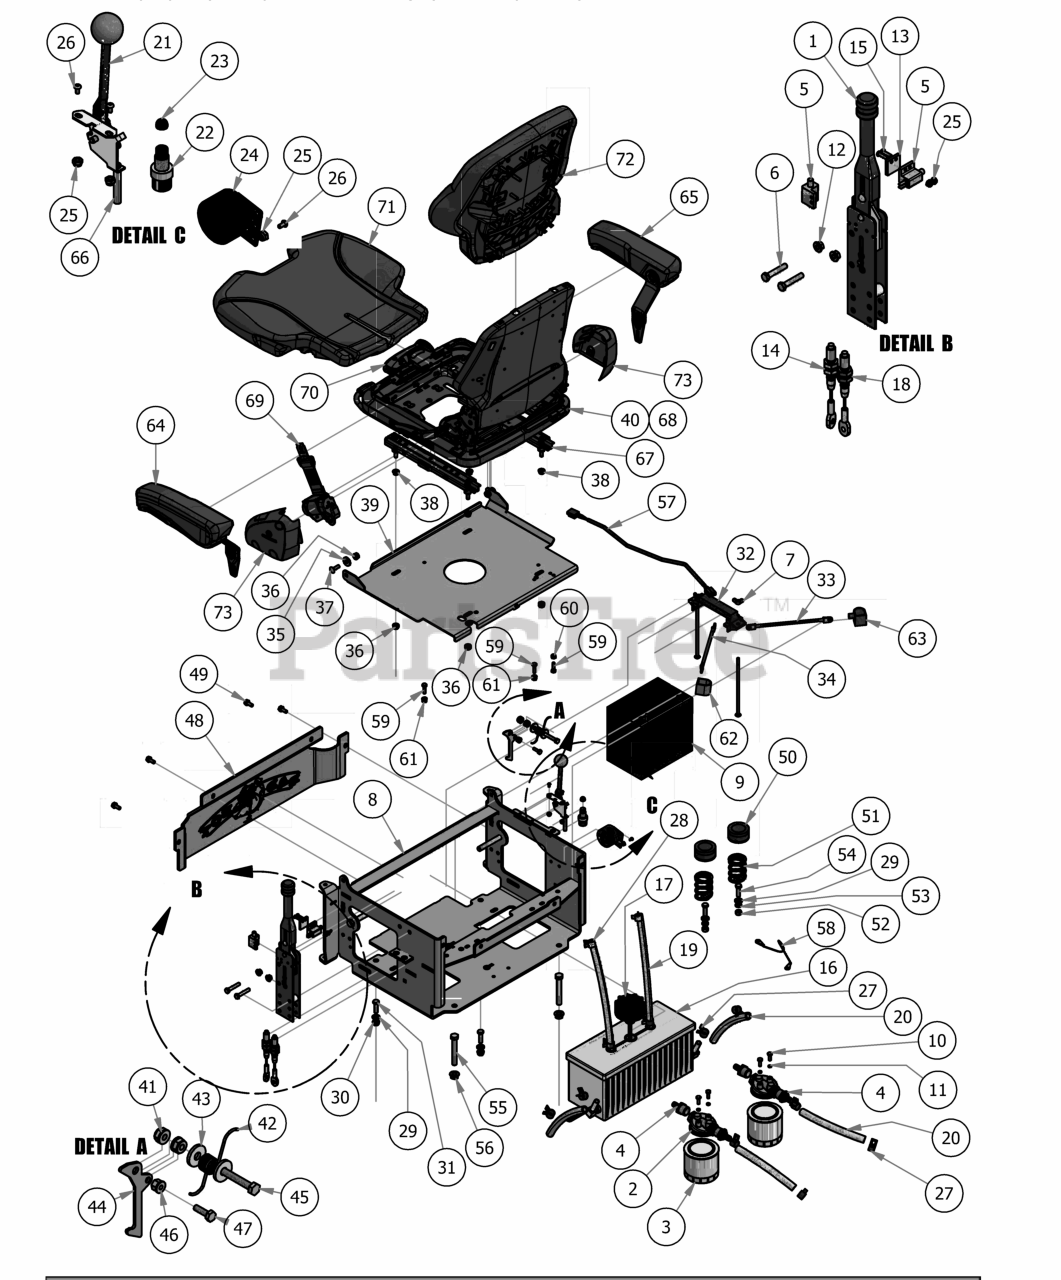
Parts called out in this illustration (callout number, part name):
1	Hand Brake Assembly
2	Filter Head
3	Hydraulic filter
4	Filter Head Fitting
6	5/16" x 1 3/4" Hex Bolt
7	1/4" Wing Nut
8	2007 Diesel Seat Frame
9	Battery - Diesel Models - I51
10	1/4" x 3/4" Hex Bolt
11	1/4" Lock Washer
12	5/16" Flange Nut w/Serrations
13	Switch Block Plastic
14	Short Brake Cable
15	1024 x 1" Allenhead Bolt
16	Aluminum Hydraulic Tank
17	Hydraulic Tank Cap
18	Long Brake Cable
19	3/8" x 32" Clear Hose
20	1/2" x 9 1/4" Braided Hose
21	Universal Throttle Head
22	Momentary Start Switch
23	Start Switch Boot - Diesel
24	Heat Warning Piezo Buzzer
25	#10 Nylock Nut
26	1024 X 5/8" Buttonhead Bolt
27	1/2 Hose Clamp
28	3/8 hose clamp
29	3/8" Flat Washer
30	3/8" Flange Nut
31	3/8" x 1 1/4" Hex Bolt
32	Battery Hold Down
33	Black Battery Cable - Diesel
34	Red Battery Cable - Diesel
35	.360 ID Plastic Washer
36	5/16-18 Nylon Flange Nut
37	5/16" x 1" Carriage Bolt
38	5/16" Flange Nut
39	Seat Plate
40	Grammer Seat With Seatbelt
41	5/16-18 Nylon Flange Nut
42	Torsion Spring for Seat latch
43	.360 ID Plastic Washer
44	Seat Latch Lever
45	5/16-18 X 2 Hex C/S (GR.5) ZC
46	1/4-20 Nylon Insert flange Nut
47	1/4-20 x 1-1/4 GR 5 Hex Bolt
48	Cooler Cover
49	5/16 x 3/4 washer head type F screw
50	Seat Spring Cap Cover
51	Seat Spring
52	3/8" Hex Nut
53	3/8" Lock Washer
54	3/8" x 1 1/2" Hex Bolt
55	1/2 x 3 1/2 Flange Bolt Grade 8
56	1/2" Flange Nut
57	Seat Switch Adapter
58	Seat Cable
59	1/4-20 x 1 GR 5 hex bolt zinc
60	1/4 Nylock Nut
61	1/4-20 Nylon Insert flange Nut
63	Black Boot For Ground Cable
64	Left Armrest Kit for Grammer Seat
65	Right Armrest Kit for Grammer Seat
66	Diesel Throttle Cable Only
67	Rails for Grammer Seat (Pair)
68	Grammer Seat (Black and Orange)
69	Seat Belt Kit for Grammer Seat
70	Grey Handle Assembly
71	Black Seat Cushion for Grammer Seat
72	Black Back Cushion for Grammer Seat
73	Black Plastic Side Covers for Grammer Seat
